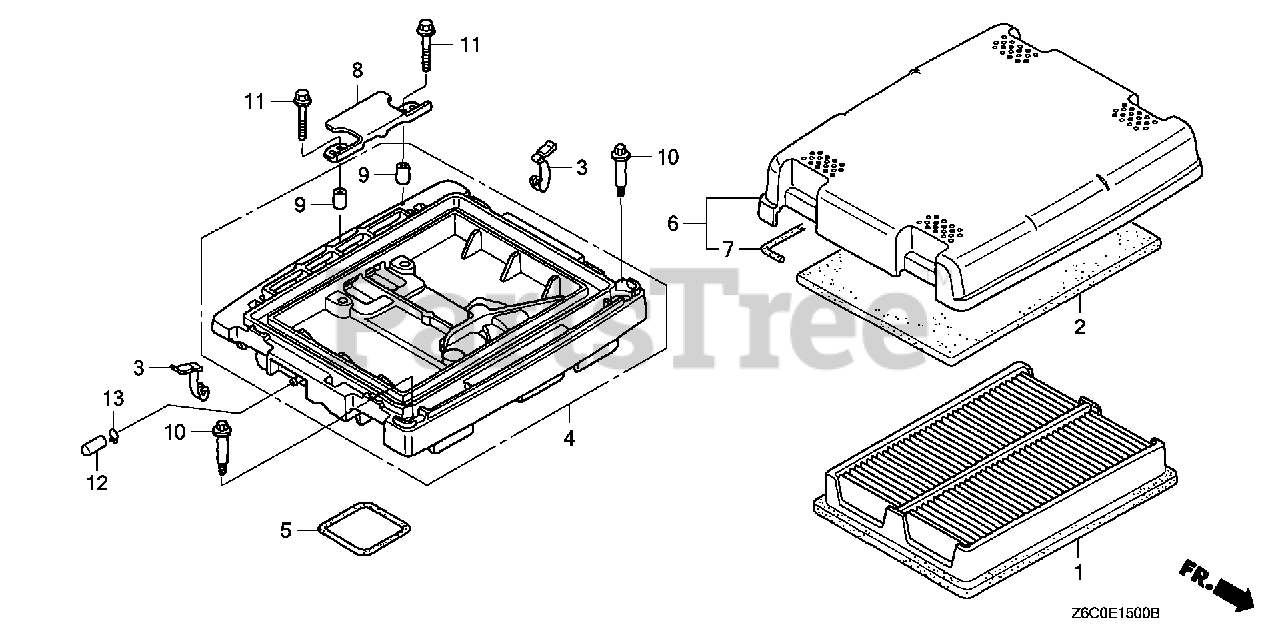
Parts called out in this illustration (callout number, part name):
1	ELEMENT, AIR CLEANER
2	FILTER (OUTER)
3	CLIP, AIR CLEANER
4	HOUSING COMP., AIR CLEANER
4	HOUSING, AIR CLEANER
5	SEAL, AIR CLEANER HOUSING
6	COVER ASSY., AIR CLEANER
7	SEAL, AIR CLEANER COVER
8	PLATE, AIR CLEANER SETTING
9	COLLAR A, AIR CLEANER
10	BOLT, SPECIAL (5MM)
11	BOLT, FLANGE (6X28)
12	CAP, SEALING
13	CLIP, TUBE (B10)
